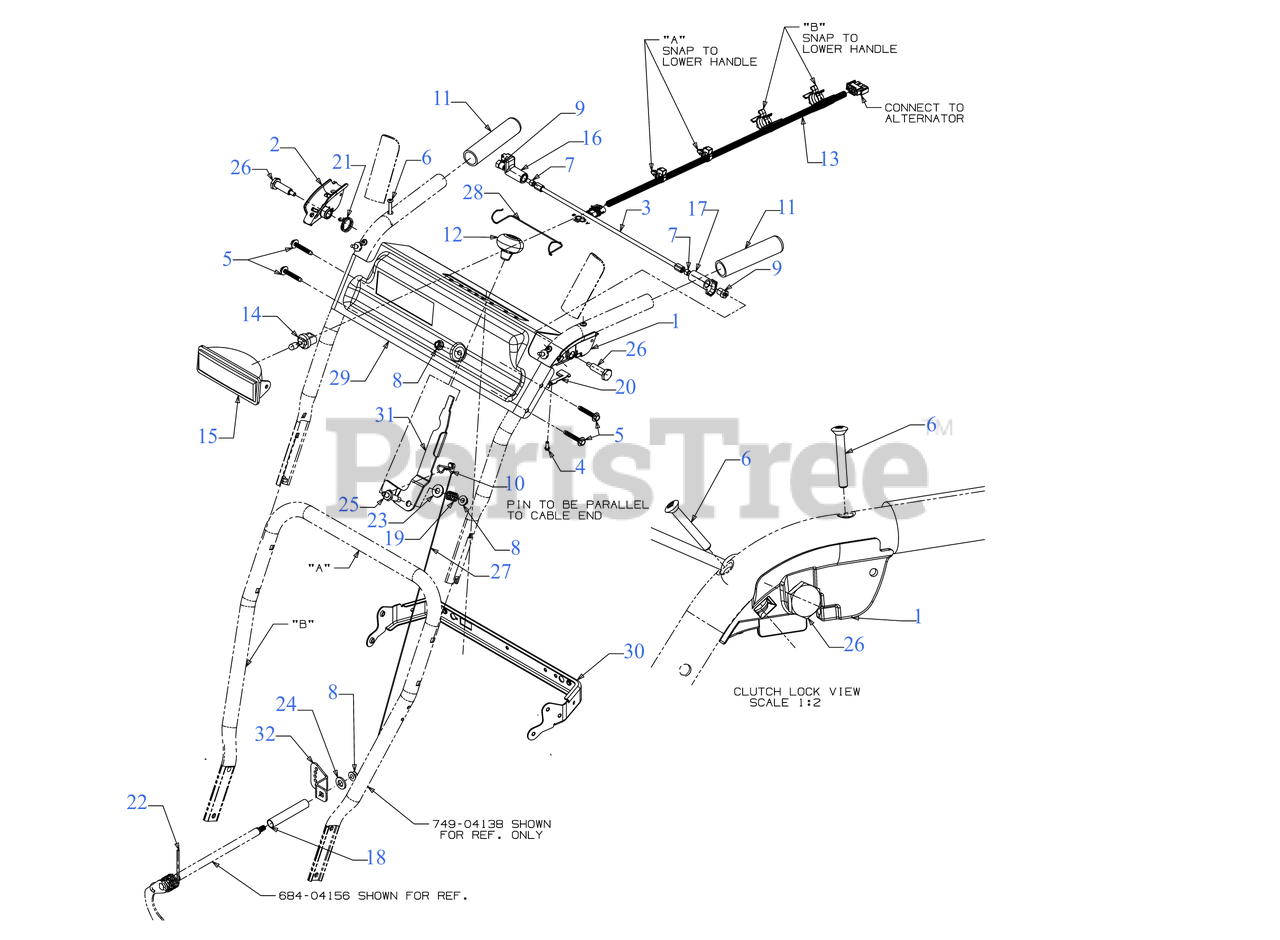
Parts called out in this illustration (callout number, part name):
1	CLUTCH LOCK HANDLE ASSEMBLY (LH)
2	CLUTCH LOCK HANDLE ASSEMBLY (RH)
3	PIVOT ROD
4	SCREW #8-16 x .50
5	SCREW 1/4-20 x 1.625
6	SCREW #10-24 x 1.375
7	SCREW 1/4-20 x .50
8	FLANGE LOCK NUT 5/16-18
9	HEX NUT W/PATCH
10	INTERNAL COTTER PIN
12	SHIFT KNOB
13	HALOGEN HEADLGHT HARNESS
14	HALOGEN BULB
15	LAMP HOUSING ASSEMBLY
16	LOCK PLATE
17	CLUTCH LOCK CAM
18	COVER .505 X .635 X 3.64
19	COMPRESSION SPRING
20	CLUTCH SPRING
21	TORSION SPRING
22	TORSION SPRING
23	FLAT WASHER .385X.870X.090
24	FLAT WASHER
25	SHOULDER BOLT
26	SHOULDER SCREW .437 x 1.345 1/4-20
27	SPEED SELECTOR CABLE (STEEL)
28	RETAINER
29	HANDLE PANEL:STEEL (POWDER BLACK)
30	HANDLE SUPPORT BRACKET (POWDER BLACK)
31	SPEED SHIFT LEVER (POWDER BLACK)
32	SPEED SELECT SHIFT BRACKET
